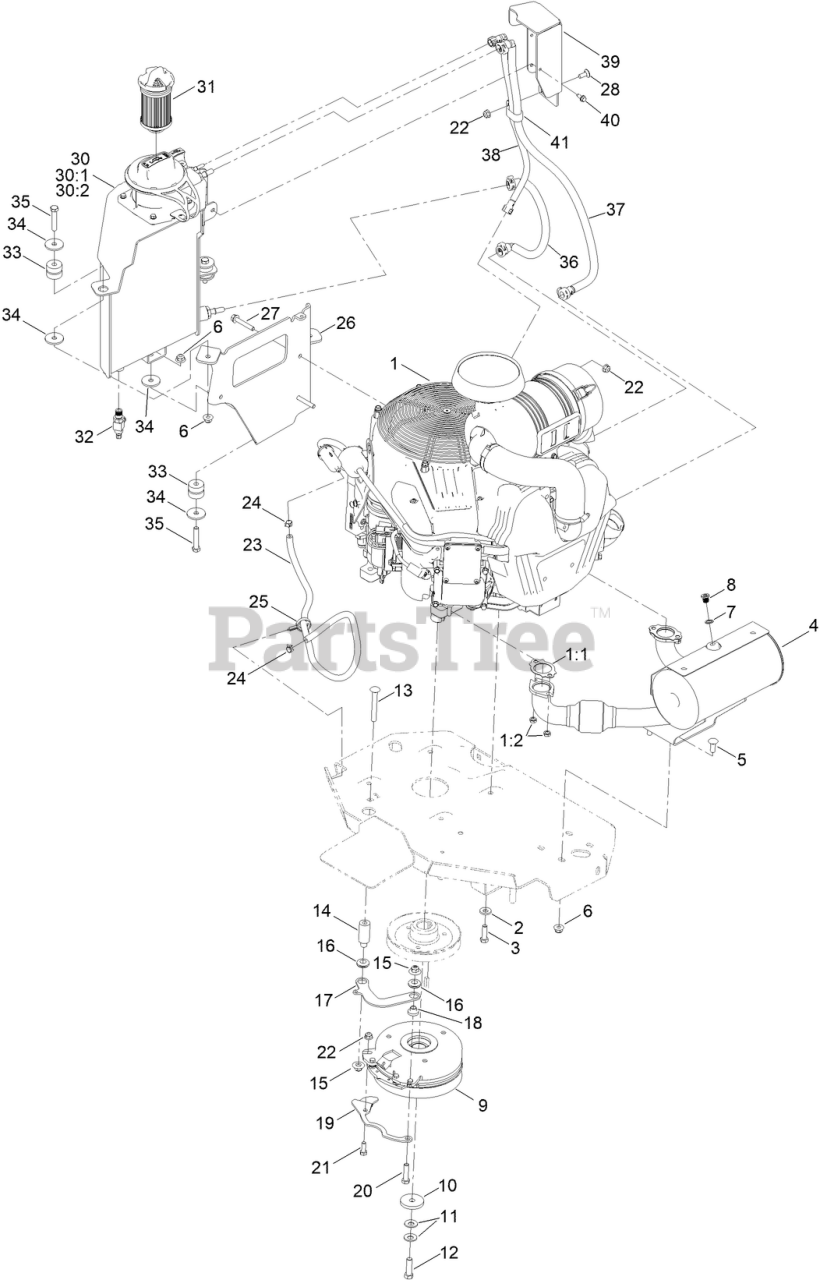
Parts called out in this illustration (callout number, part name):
1	ENGINE VANGUARD EFI
1:1	GASKET-EXHAUST
1:2	NUT-HEX
2	WASHER-BELLEVILLE
3	SCREW-HH
4	MUFFLER
5	SCREW-CARR
6	NUT-HF, NI
7	WASHER-COPPER
8	PLUG-HSH
9	CLUTCH KIT
10	WASHER-CLUTCH
11	WASHER-SPRING
12	SCREW-HH, W/LOCTITE
13	SCREW-CARR
14	SPACER
15	NUT-FLANGE, NI
16	GROMMET-RUBBER
17	LINK-ANCHOR, CLUTCH
18	SPACER
19	BELT-GUIDE
20	SCREW-HH
21	SCREW-HH
22	NUT-HF, NI
23	HOSE-FUEL
24	CLAMP-HOSE
25	CLAMP-HOSE
26	MOUNT-TANK, OIL
27	SCREW-HHF
28	SCREW-CARR
30	RESERVOIR-OIL
30:1	OIL DIPSTICK ASM
30:2	OIL TANK CAP ASM
31	FILTER-OIL
32	VALVE-OIL DRAIN
33	ISOLATOR-TANK
34	WASHER
35	SCREW-HH
36	HOSE-SUPPLY
37	HOSE-SCAVENGE
38	HOSE-VENT
39	GUARD-HOSE
40	SCREW-HWH
